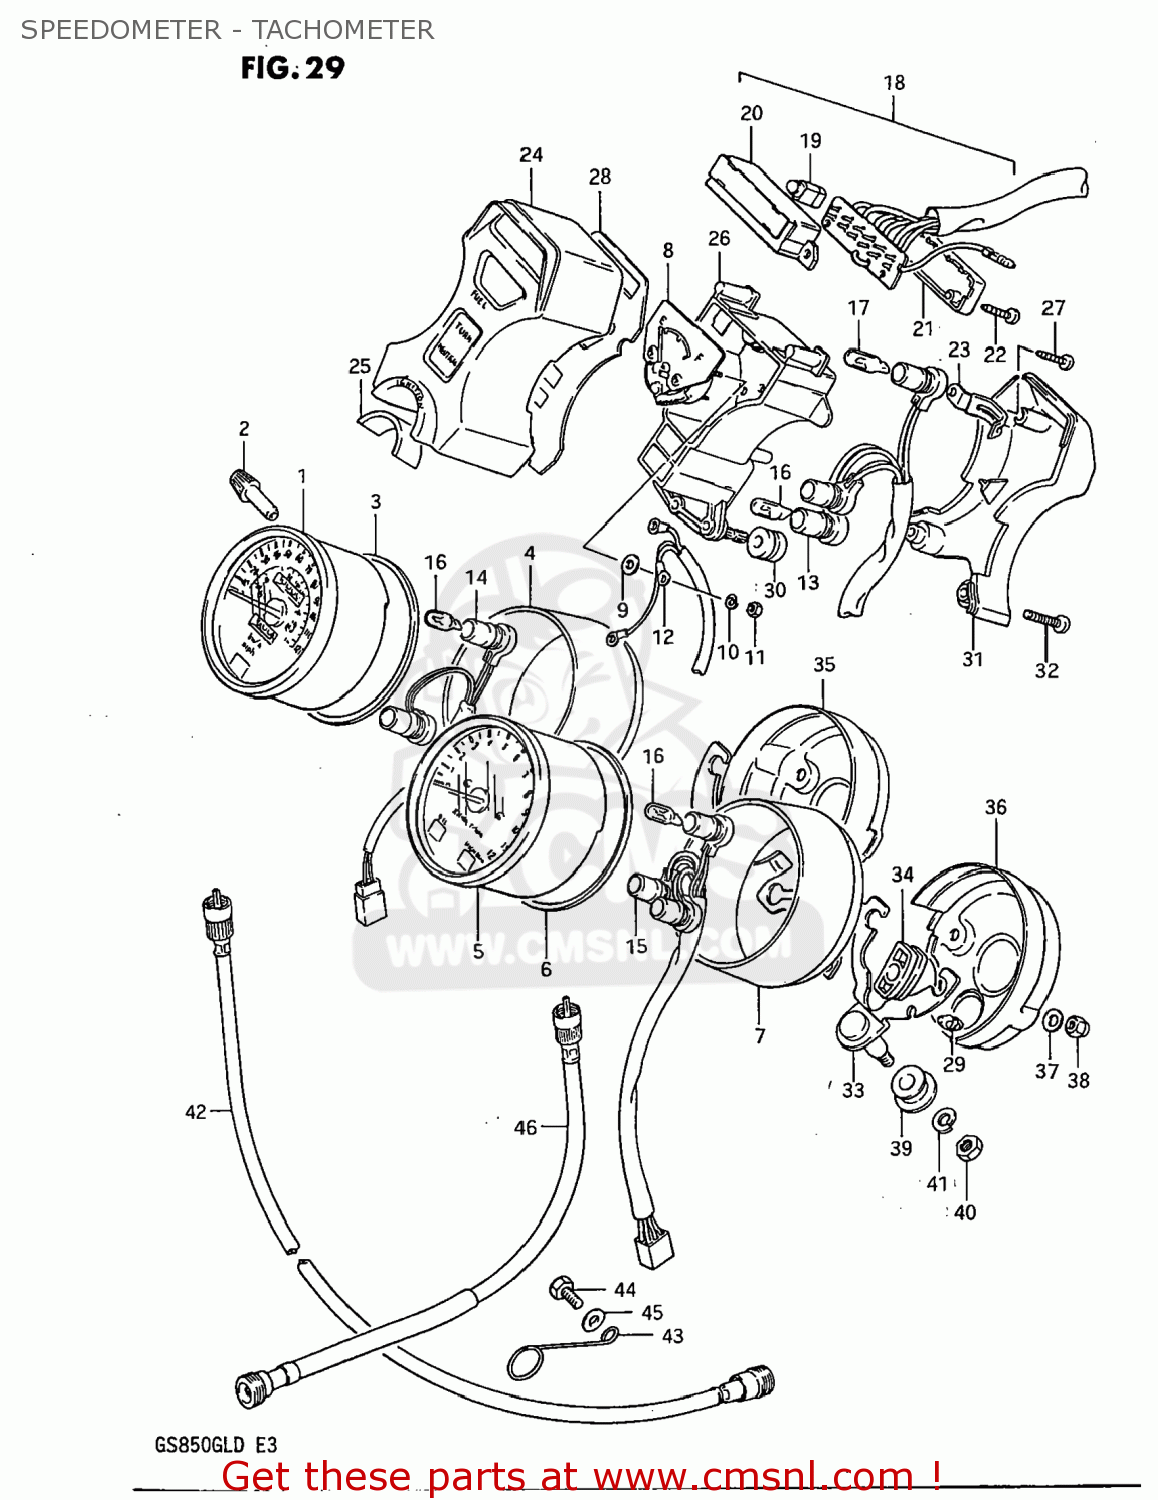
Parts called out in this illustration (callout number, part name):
1	SPEEDOMETER ASSEMBLY
2	KNOB
3	CUSHION,SPEEDOMETER
4	COVER,SPEEDOMETER
5	TACHOMETER
6	CUSHION,SPEEDOMETER
7	COVER,TACHOMETER
8	METER,FUEL
9	WASHER,FUEL METER
10	LOCK WASHER
11	NUT 3MM
12	SOCKET,FUEL METER
13	SOCKET,PILOT CASE
14	SOCKET,SPEEDOMETER
15	SOCKET,TACHOMETER
16	BULB(12V3.4W,T10)
17	BULB(12V1.7W,T10,WB121)
18	INDICATOR ASSEMBLY,GEAR POSITION
19	BULB(14V1.12W)
20	CASE,GEAR INDICATOR
21	COVER,LWR
22	SCREW,GEAR INDICATOR
23	CLAMP,CORD
24	CASE,PILOT BOX
25	SEAL,IGNITION SWITCH
26	CASE,PILOT BOX,INNER
27	SCREW,INDICATOR
28	PLATE,PILOT BOX
29	CUSHION
30	CUSHION,PILOT BOX
31	COVER,PILOT BOX,UNDER
32	SCREW
33	BRACKET,COMBINATION METER
34	CUSHION,METER
35	COVER,METER,UNDER
36	PLATE,TACHOMETER UNDER
37	WASHER
38	NUT
39	CUSHION,METER BRACKET
40	NUT
41	LOCK WASHER
42	CABLE ASSEMBLY,SPEEDOMETER
43	CLAMP,SPEEDOMETER CABLE
44	BOLT, UPPER
45	WASHER
46	CABLE ASSEMBLY,TACHOMETER
